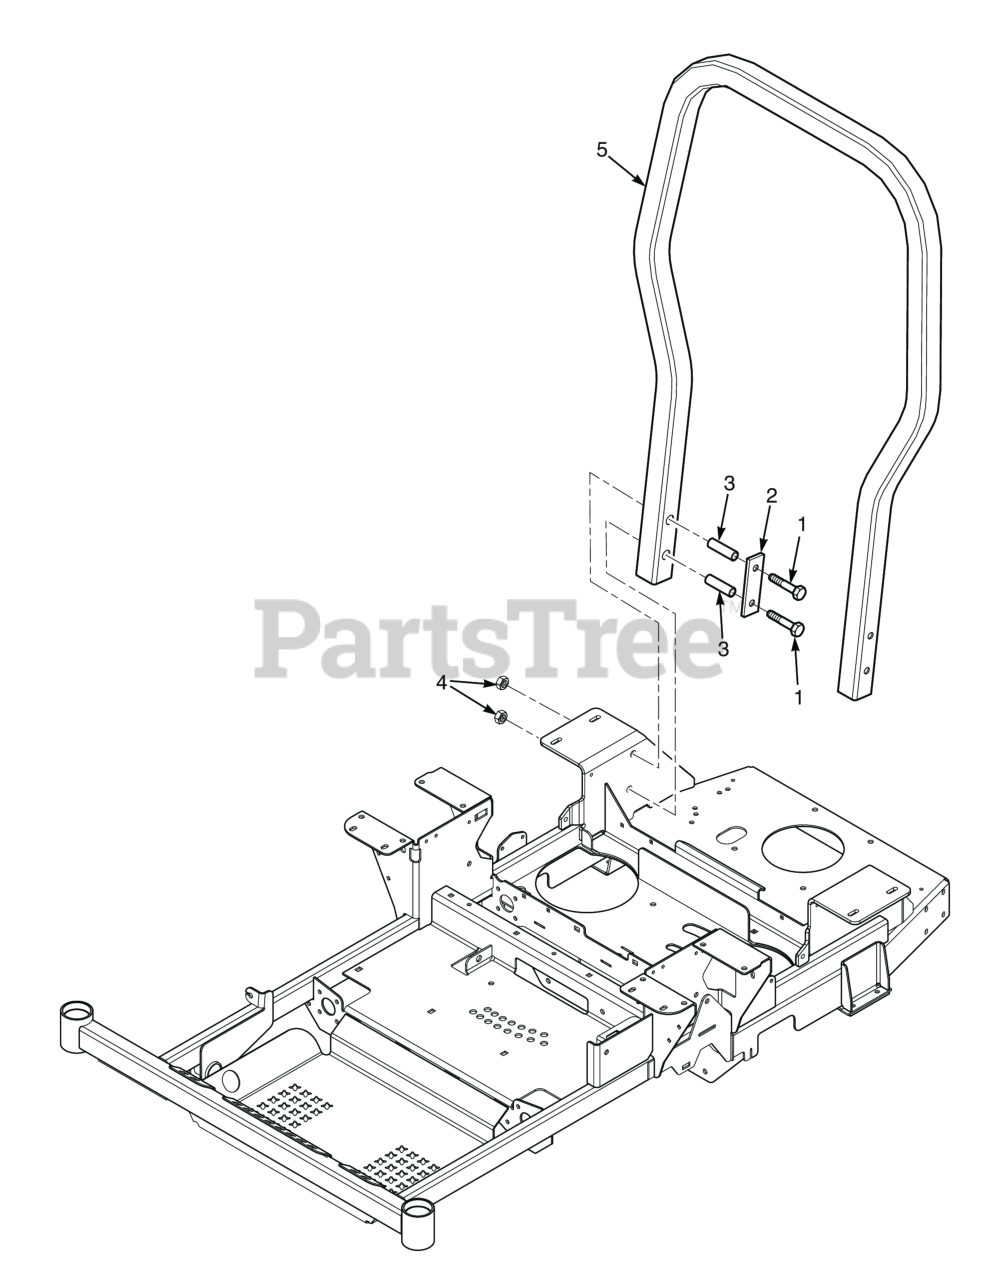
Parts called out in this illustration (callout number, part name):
1	Bolt, Hex Head 1/2-13 x 3-1/4" Gr. 8
2	ROPS Mounting Plate
3	Bushing, SFZ ROPS
4	Nut, Elastic Stop 1/2-13, (STT-52 & STTII-52)
5	ROPS, SFZ48H, SFZ52H
